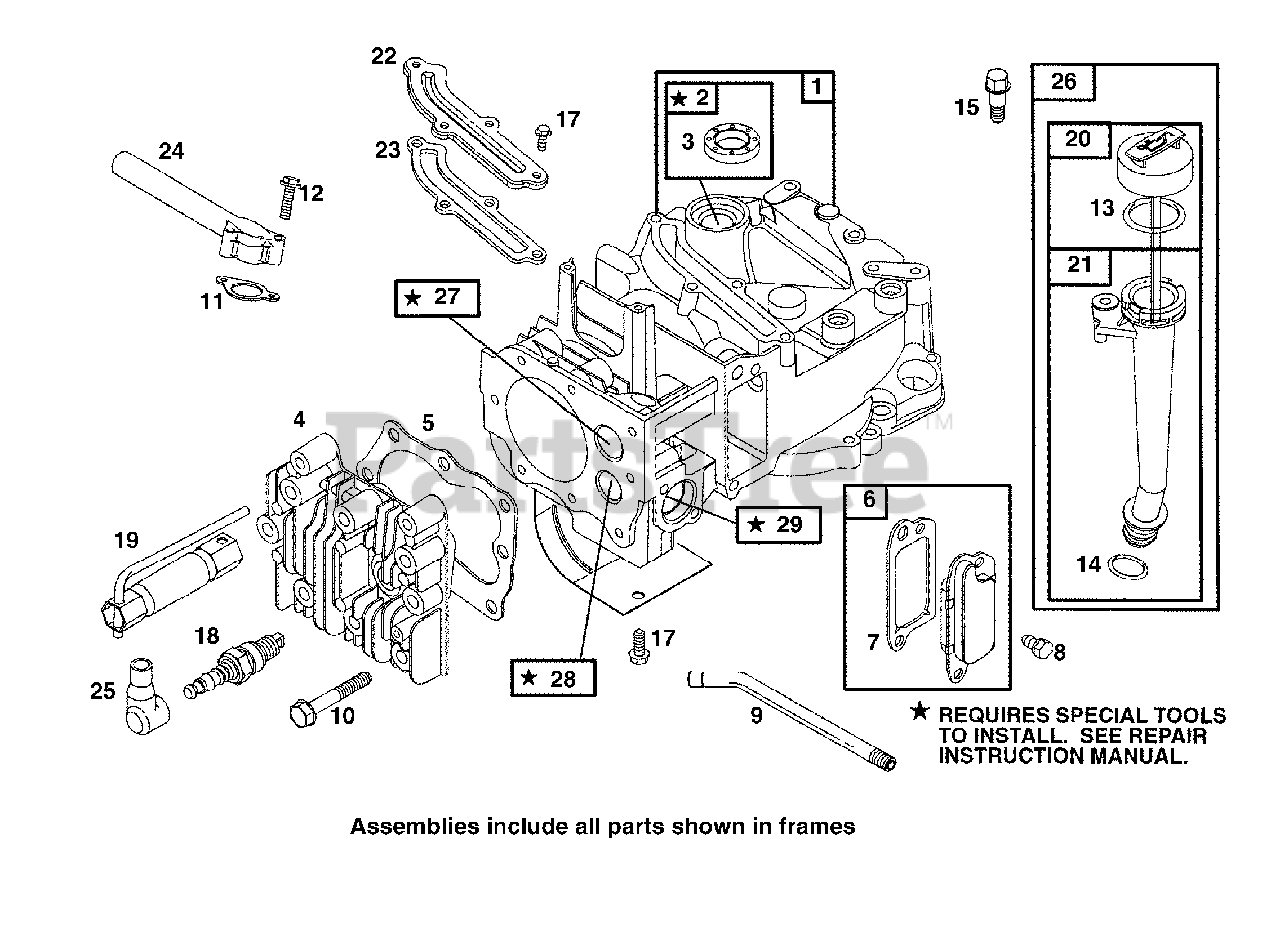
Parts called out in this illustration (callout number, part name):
1	Cylinder Assembly
2	Bushing/Seal Kit
3	Oil Seal
4	Cylinder Head
5	Cylinder Head Gasket
6	Breather Assembly
7	Breather Gasket
8	Hex Screw
9	Breather Tube
10	Hex Screw
11	Intake Gasket
12	Hex Screw
13	O-Ring Seal
14	O-Ring Seal
15	Shoulder Screw
17	Hex Screw
18	Spark Plug
19	Spark Plug Wrench
20	Dipstick
21	Oil Filler Tube
22	Breather Passage Cover
23	Breather Passage Gasket
24	Intake Manifold
25	Spark Plug Elbow
26	Dipstick/Tube Assembly
27	Valve Seat
28	Valve Seat
29	Guide Bushing
